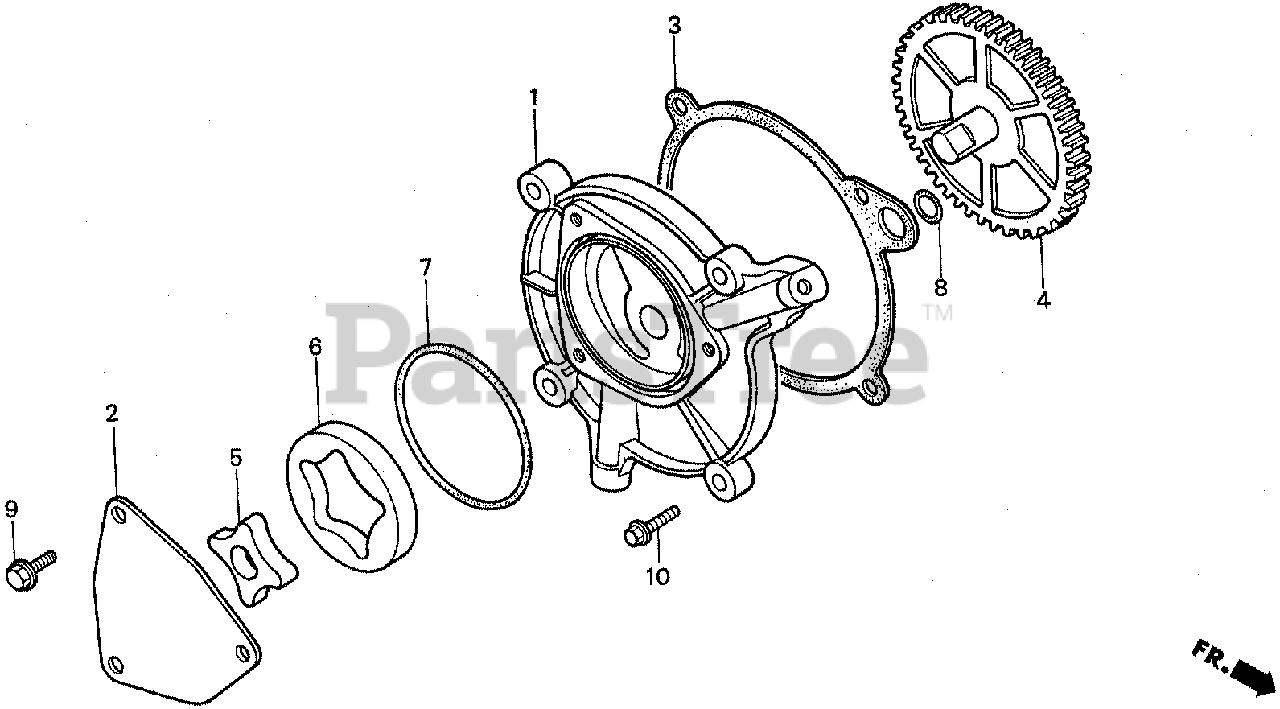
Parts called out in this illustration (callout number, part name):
1	BODY, OIL PUMP
2	COVER, OIL PUMP
3	GASKET, OIL PUMP
4	GEAR ASSY., OIL PUMP
5	ROTOR (INNER)
6	ROTOR (OUTER)
7	O-RING (45X2.5) (ARAI)
7	O-RING, PUMP COVER
8	O-RING (10.8X2.4) (ARAI)
9	BOLT, FLANGE (6X12)
10	BOLT, FLANGE (6X28)
